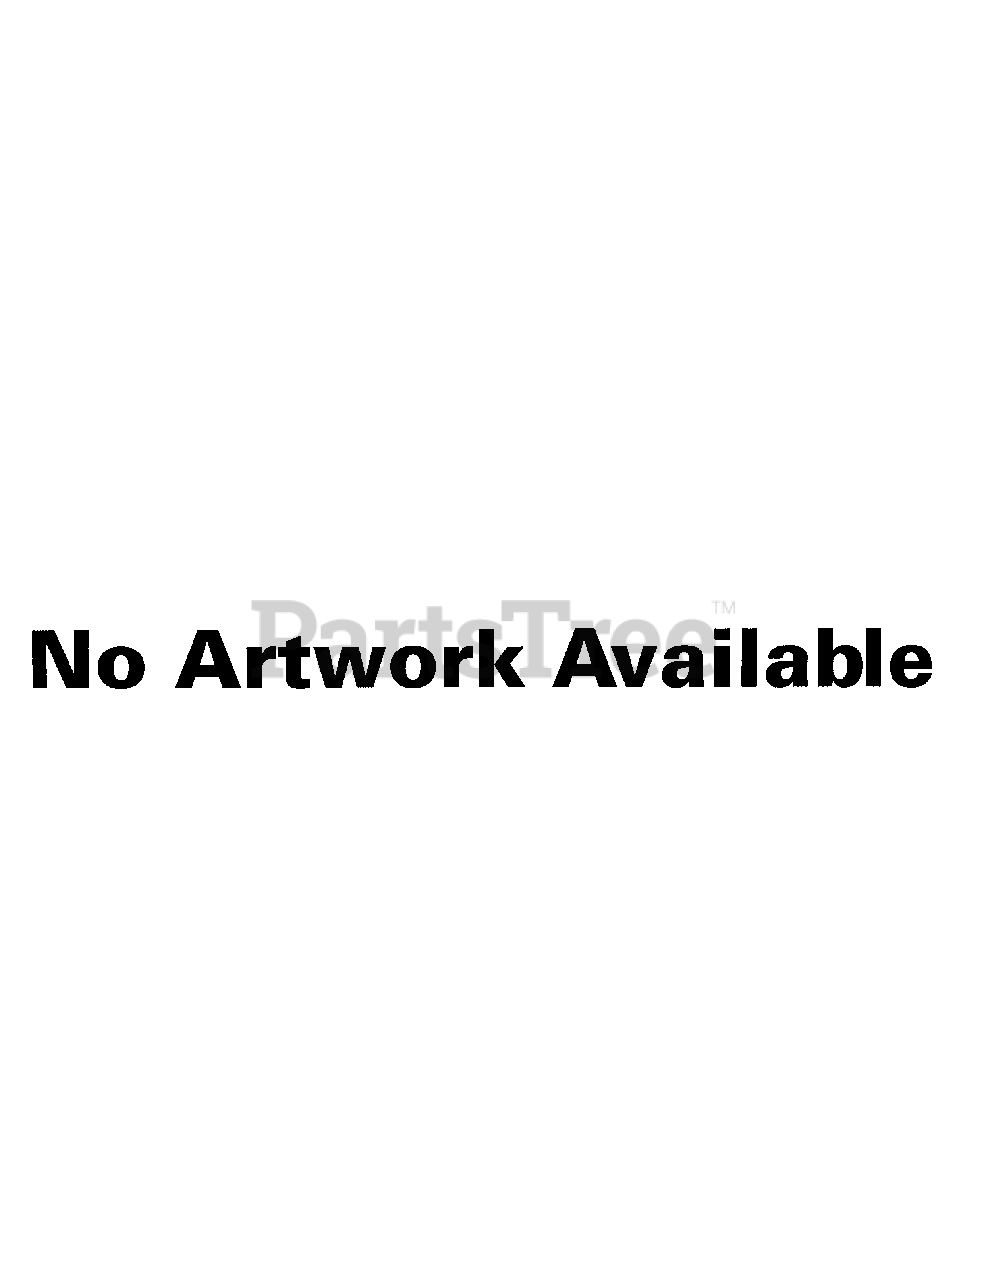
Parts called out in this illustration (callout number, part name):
1	GASKET KIT
2	GASKET, CRANKCASE
3	GASKET, CYLINDER
4	GASKET, INTAKE
5	GASKET, INTAKE
6	HEAT SHIELD, EXHAUST
7	GASKET, EXHAUST
8	PLUG & FILTER KIT - YOU CAN
9	FILTER, FUEL
10	FILTER, AIR - DOUBLE LAYER
11	SPARK PLUG - BPMR8Y
12	FUEL SYSTEM KIT - YOU CAN
13	VENT ASSY
14	CLIP Ø6
15	PIPE, FUEL 3×5×90 BLACK
16	PIPE, FUEL 3×5×74 BLACK
17	PIPE, FUEL 3×6×80 CLEAR
18	GROMMET, FUEL Ø5
19	CONNECTOR, PIPE Ø5ר3.5
20	PIPE, FUEL 3×5×130 BLACK
21	FILTER, FUEL
22	GASKET, FUEL CAP
23	BULB, PURGE
